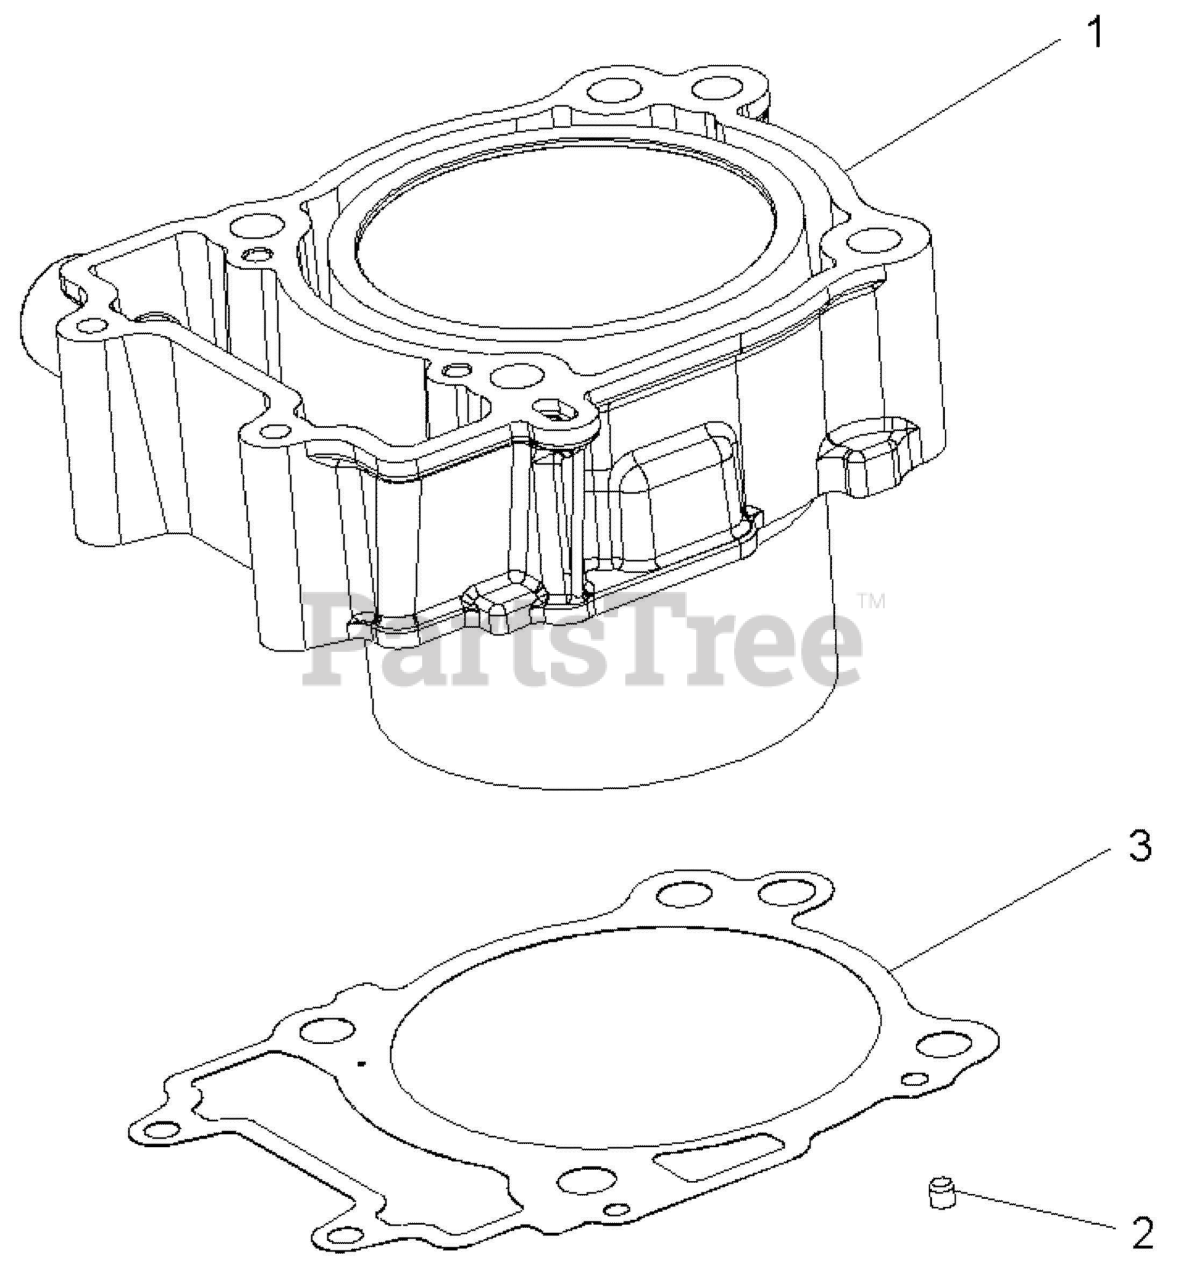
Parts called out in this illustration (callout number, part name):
1	ASM-CYLINDER,99MM
2	PIN-DOWEL,M6X10
3	GASKET-BASE
